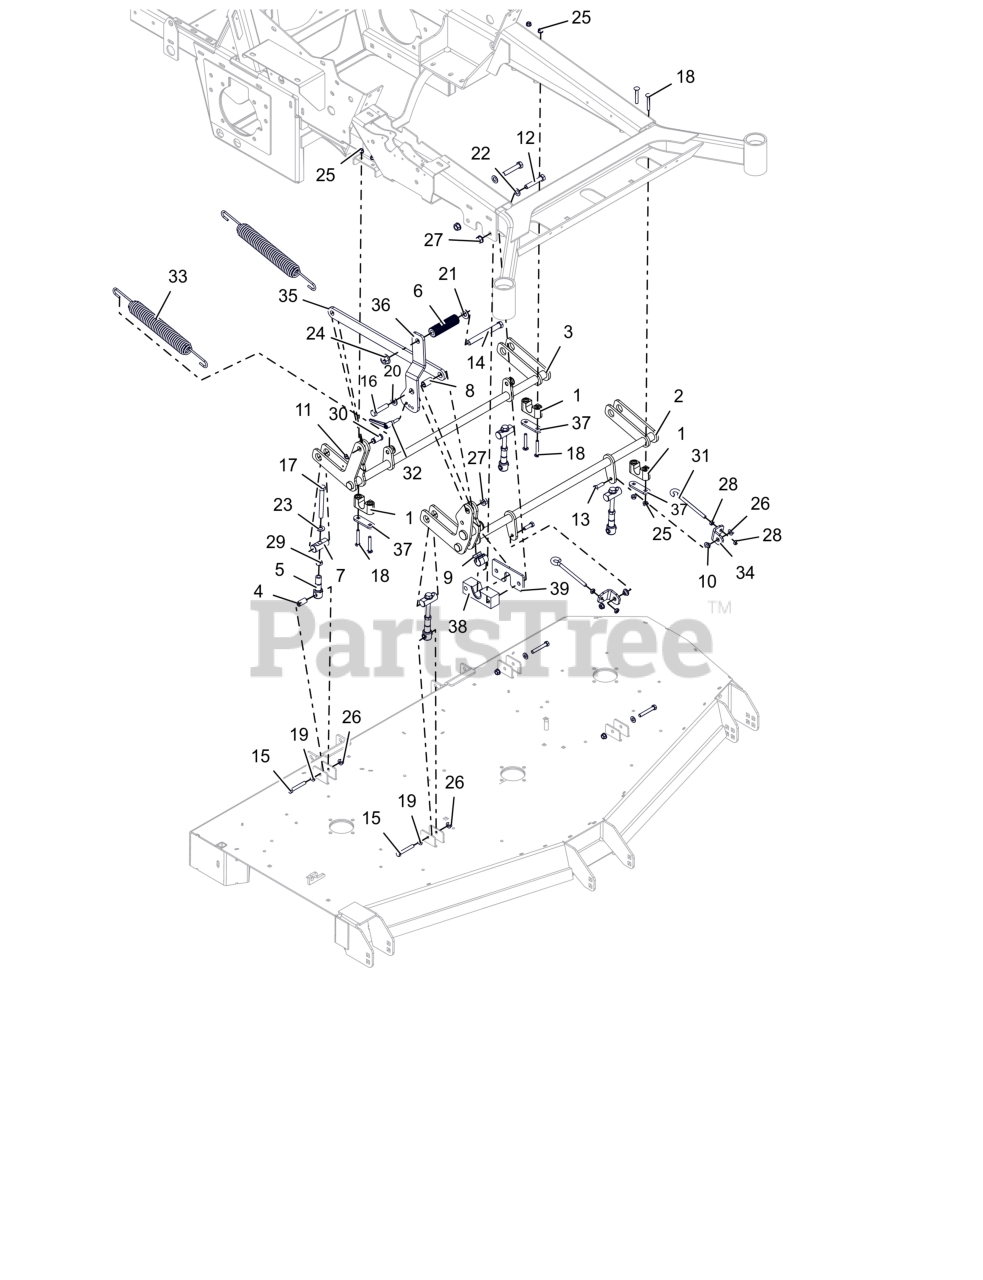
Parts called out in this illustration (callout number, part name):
1	ASM-BUSHING, DECK LIFT
2	WLDMT, FRONT DECK LIFT (BLACK)
3	WLDMT, REAR DECK LIFT (BLACK)
4	SPACER, DECK LEVELING
5	LINK, DECK LIFT FORMED
6	ROD, FOOT PEDAL (BLACK)
7	PIN, DECK LIFT
8	SPCR, SLV .531x.75x1.449
9	BUSHING, SHAFT
10	BSHG-FLG .385X.500X.875X.406
11	RG-RTNG-EXT .625X.050
12	BLT,HEX .50-13X2.75 G5 ZCC
13	BLT, HEX .38-16X1.25 G5 ZCC
14	BLT, HEX .62-11X5.50 G5 FBP
15	BLT, HEX .38-16X2.50 G8 ZCC
16	BLT, HEX .50-13X2.25 G5 ZCC
17	BLT, HEX 0.5-13X4.5S GR5 ZCC
18	BLT, RHSSN.31-18X2.25 G5 ZCC
19	WSHR,FLT .406X.812X.065 ZCC
20	WSHR,FLT .531X1.062X.095 ZCC
21	WSHRFLT 5/8SAE CARBHARD FBP
22	WSHR, FLT .531X1.00X.063 ZCC
23	WSHR, FLT .557X1.040X.102 ZCC
24	NUT,FLG-TOP LK .625-11 FBP
25	NUT,LK-CTR-FLG .31-18 GF ZCC
26	NUT-LK-CTR-FLG .375-16 GF ZCC
27	NUT-LK-CTR-FLG .500-13 GG ZCC
28	NUT-JAM .375-16 G2 ZCC
29	NUT-JAM .500-13 G2 ZCC
30	PIN, CLEVIS .625 SNAP RING
31	BOLT, EYE .38-16X4.50 .62DIABZ
32	HANDLE, CLAMPING
33	SPRG, DECK LIFT
34	BRKT, SPRING ANCHOR (BLACK)
35	LINK, DECK LIFT (BLACK)
36	ARM, ADJUSTABLE FOOT PEDAL (BLACK)
37	PLATE, PT600 BEARING SUPPORT (BLACK)
38	BUSHING, DECK LIFT
39	PLATE, SHAFT RETAINER (RED)
